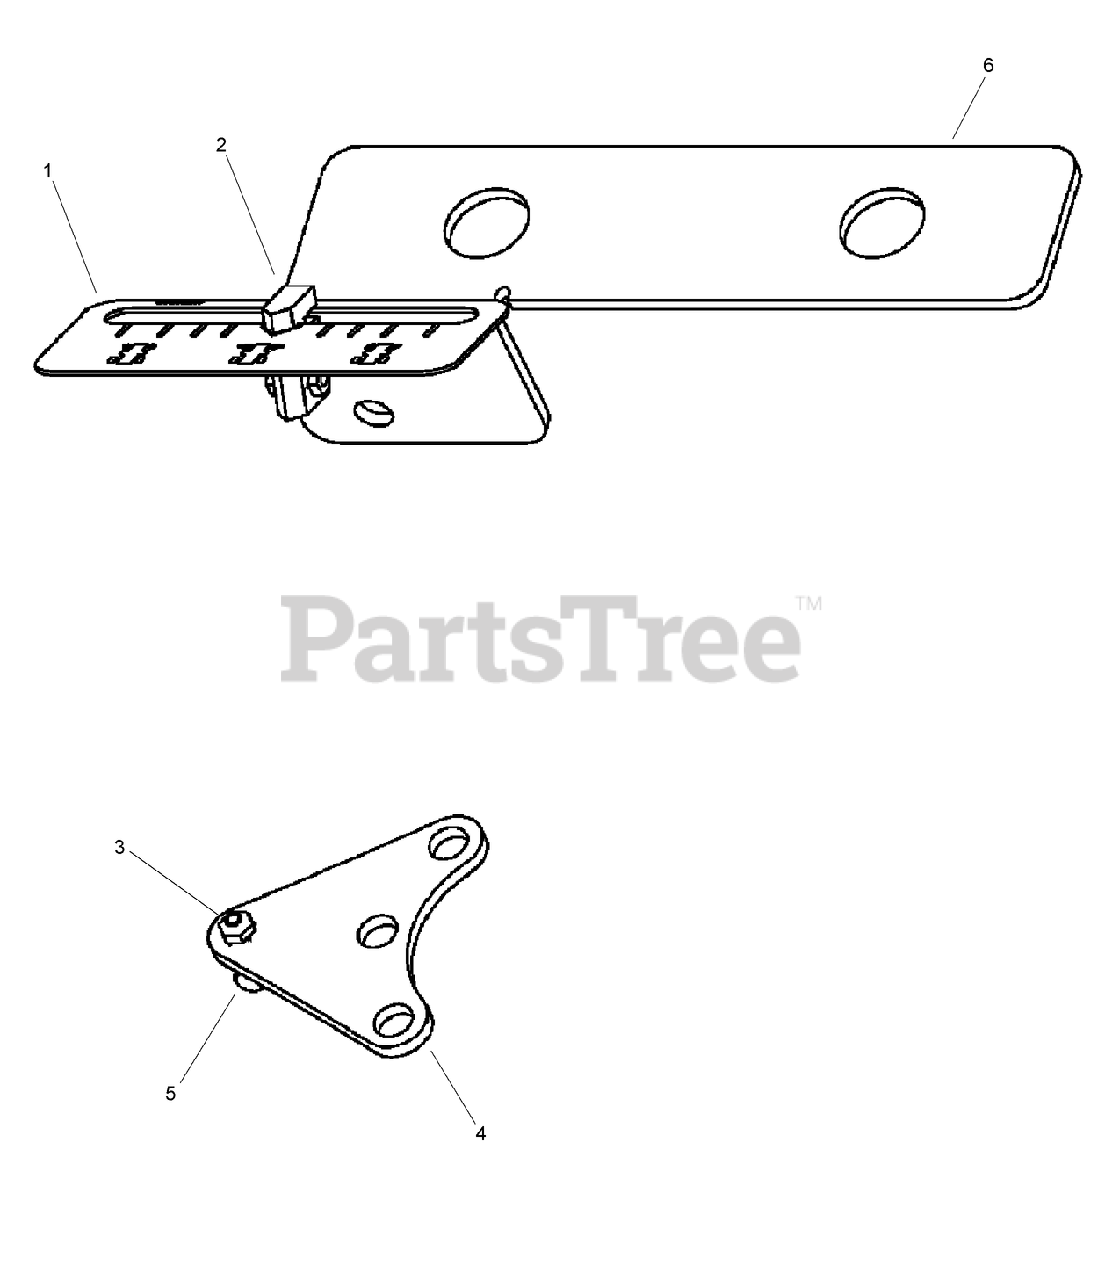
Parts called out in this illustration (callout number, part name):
1	DECAL-Rear Steering Indicator
2	POINTER-INDICATOR, POSITION
3	NUT-KEPS Ext T Washer #10-32 UNF ZP
4	PLATE-Steering Indicator
5	JOINT-Ball
6	MOUNT-Rear Steering Indicator Cable
